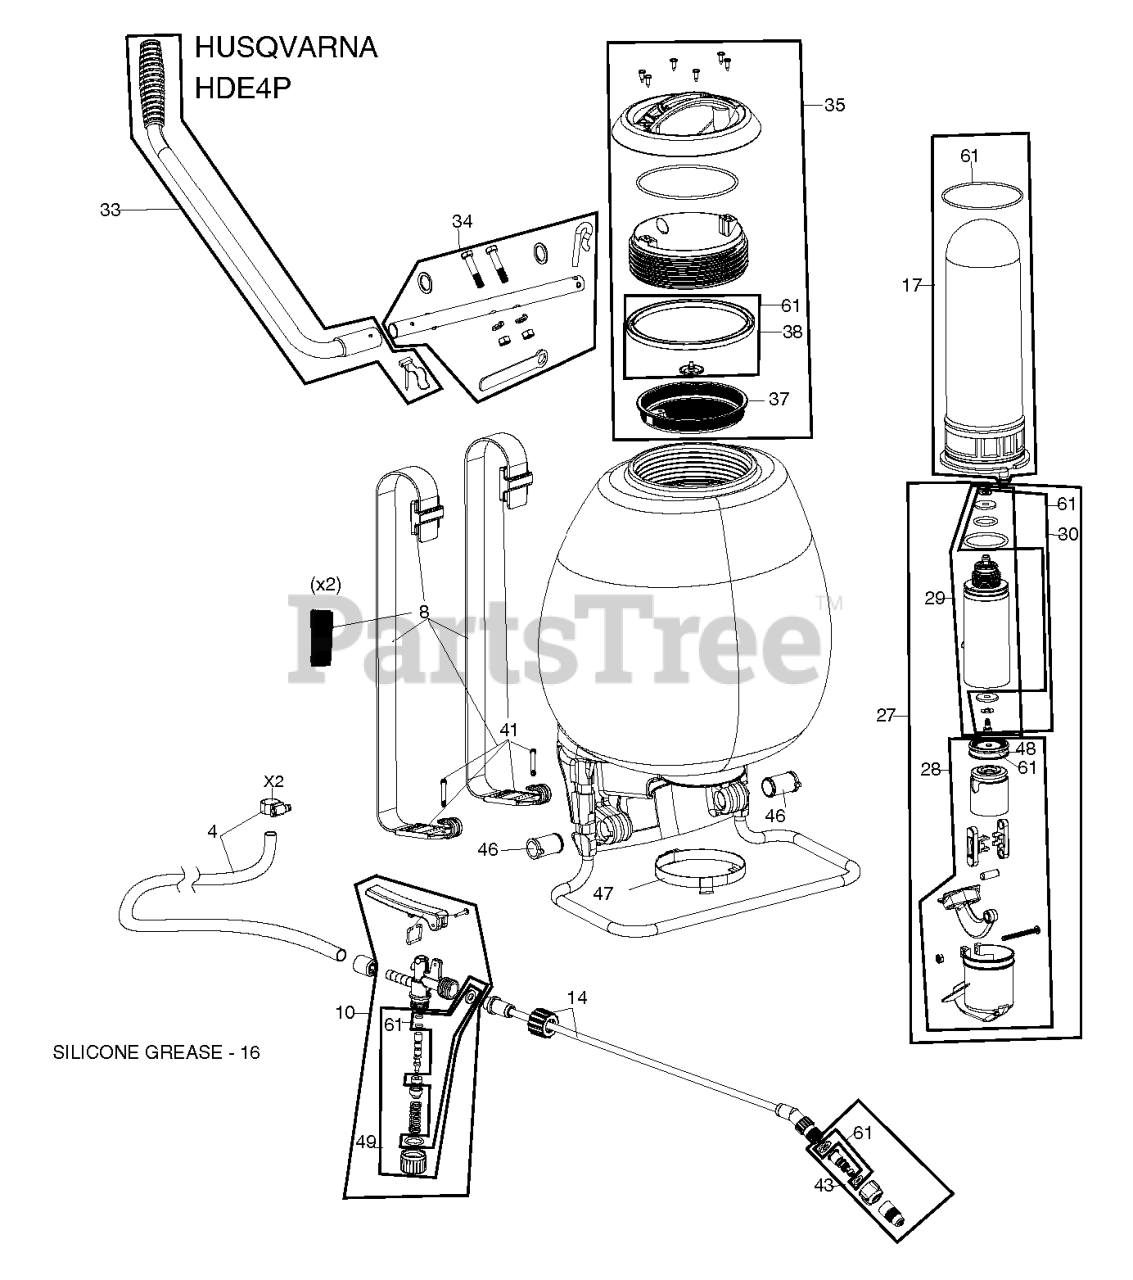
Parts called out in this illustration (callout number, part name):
4	HOSE AND 2 HOSE CLAMPS
8	SHOULDER STRAP ASSEMBLY
10	SPRAY GUN W/GRIP & PLASTIC HND
14	FIBERGLASS WAND 20"
16	SILICONE GREASE
17	PRESSURE CHAMBER & ORING
27	G8 PISTON & CYLINDER COMPLETE
28	PISTON, SEAL CONNECTING RODS
29	CYLINDER ASSY
30	DIAPHRAGM & VITON SEALS
33	PUMP HANDLE, BLACK
34	PUMP LEVER
35	BACKPACK LID & SEAL W/HANDLE
41	BUCKLE & HOOK FOR STRAP
43	MET PUMP LVR W/LOCK RPINS WSHR
46	NYLON BEARING
47	RETENTION CLAMP
48	PISTON CUP G8
49	SPINDLE SET W/ VITON &
61	SEAL SET COMPLETE HDE4P
